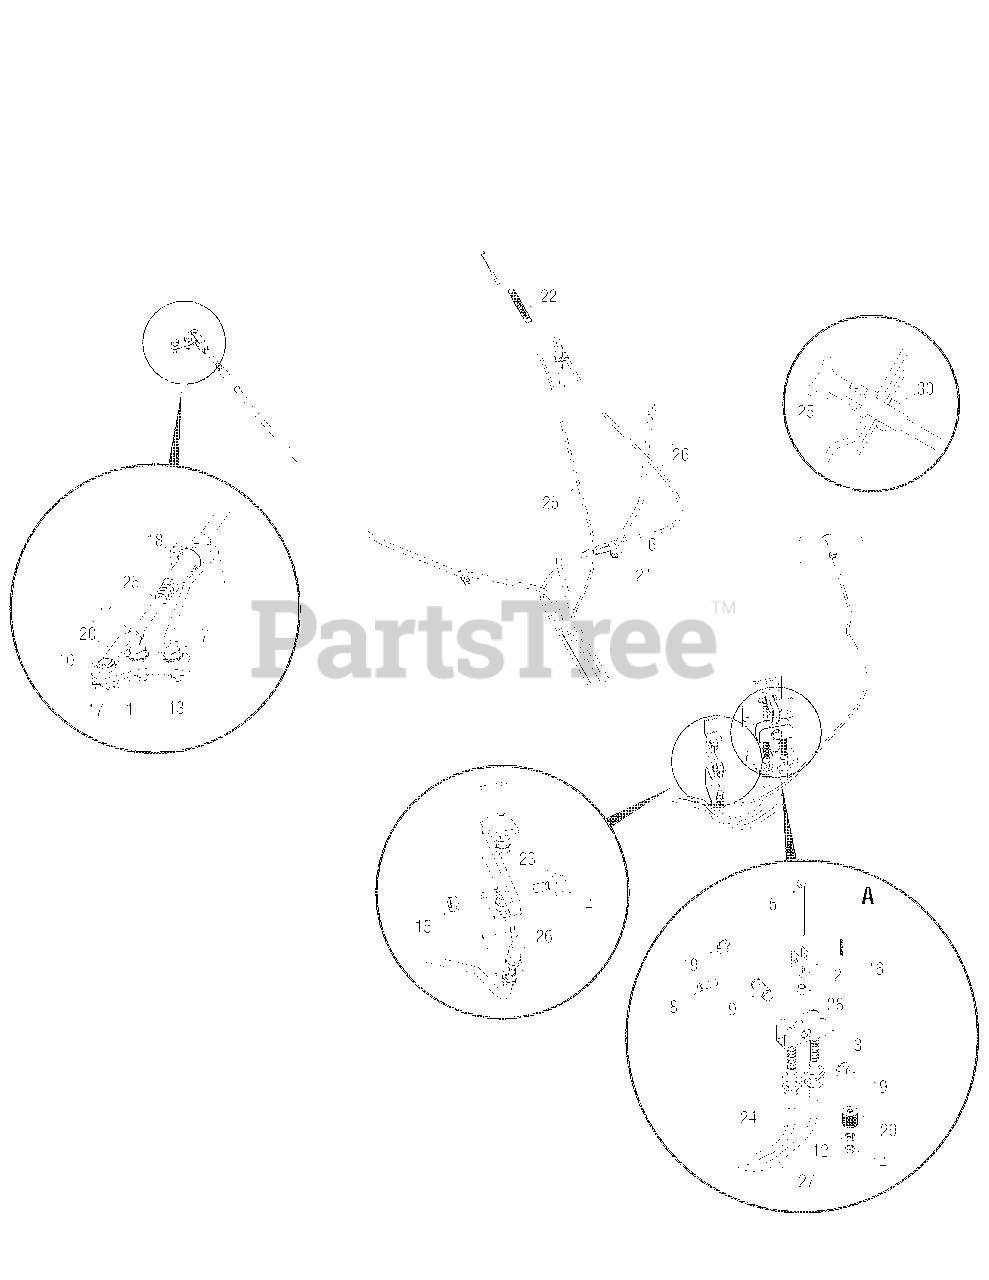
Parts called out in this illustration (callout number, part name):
1	Plate, Arm Brake
2	Mount,Cable
3	Bracket, Equalizer
4	Screw, Shoulder, .375 x .375
5	Screw, 5/16-18 x 3.5
6	Screw, Self-Tapping
7	Washer, 5/16-18 x .875
8	Pin, Clevis 375 x .969
9	Pin, Clevis .625 OD x 1.37
10	Pin, Clevis .312 OD x 1.0
11	Nut, Jam 5/16-24
12	Nut, Hex 5/16-18
13	Nut, FlangeLock 5/16-18
14	Nut, Jam 5/16-18
15	Hexlock Nut, 5/16-18
16	Pin, Cotter, .072 x 1.13
17	Pin, Cotter 3-32 x .750
18	E-Ring for .500 Dia Shaft
19	E-Ring.625 Shaft
20	Yoke, 5/16-24
22	Extension Spring
23	Washer, .349 x .879 x .063
24	Cable, Cont., Brake
25	Cable, Control, Choke
26	Cable, Control, Throttle
27	Cable, Control, Brake, 4x2
28	Spacer, .466 OD x .443
29	Washer, Belleville, .937 x .328 x .07
30	Nut, Jamlk, 3/6-16
